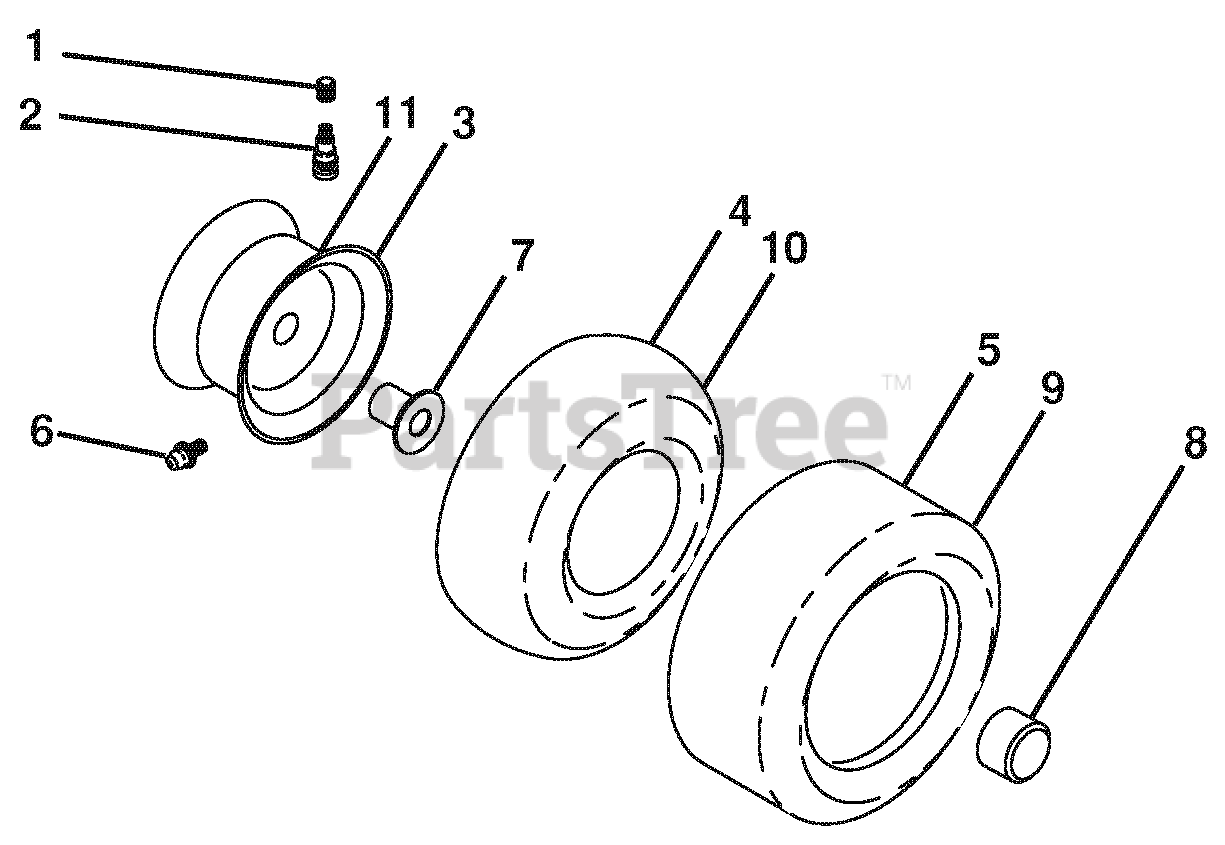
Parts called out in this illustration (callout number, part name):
1	CAP.VALVE.TIRE
2	STEM.VALVE
3	RIM.ASM.6"FRONT
4	TUBE.INNER.FRONT.#35060
5	TIRE.F.TS.15 X 6.0 - 6.SERVICE
6	FITTING, GREASE
7	BEARING FLANGE
8	CAP.HUB.AXLE.BLK.1.50 X 1.00
9	TIRE.R.TS.20 X 8-8.C.SERVICE
10	TUBE, REAR
11	RIM.ASM.8"REAR
